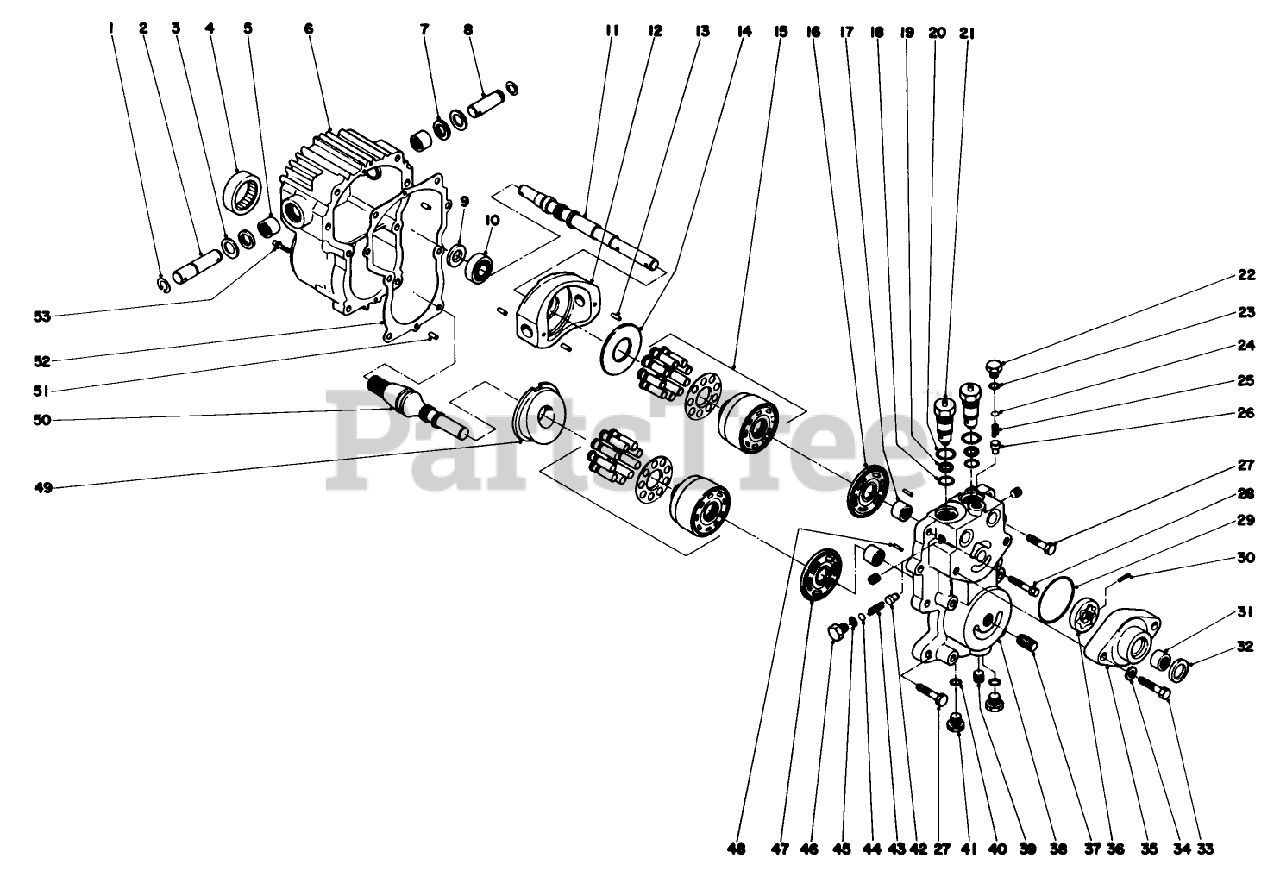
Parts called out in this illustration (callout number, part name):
1	RING-RETAINING
2	SHAFT-TRUNNION
3	WASHER-FLAT
4	BEARING-ROLLER
5	Bearing-Needle
6	Housing
7	SEAL-LIP
8	SHAFT-TRUNNION
9	Up Seal
10	BEARING-BALL
11	SHAFT-PUMP
12	Variable Swashplate
13	Pin
14	THRUST PLATE
15	Cylinder Block Kit
16	Pump Valve Plate
17	BEARING-NEEDLE
18	O-RING
19	RING-BACK UP
20	O-RING
21	Check Valve Assembly
22	PLUG-HH
23	O-Ring
24	PACK-SHIM
25	SPRING-VALVE
26	Relief Valve Cone Imp.
27	SCREW-HH
28	CAPSCREW
29	O-RING
30	Pin
31	BEARING
32	SEAL-LIP
33	SCREW-HH
34	WASHER
35	Charge Pump Housing
36	Rotor Assembly
37	UNION-FILTER
38	Center Section
39	Plastic Plug
40	"0" Ring
41	Threaded Plug (Incl. Ref. # 40)
42	Cone-Charge Relief
43	SPRING-VALVE
44	Shim Pack
45	O-RING
46	Hex Hd. Plug
47	PLATE-VALVE, MOTOR
48	PIN-DOWEL
49	Swashplate
50	Motor Shaft
51	Pin
52	GASKET
53	12 Point Capscrew
